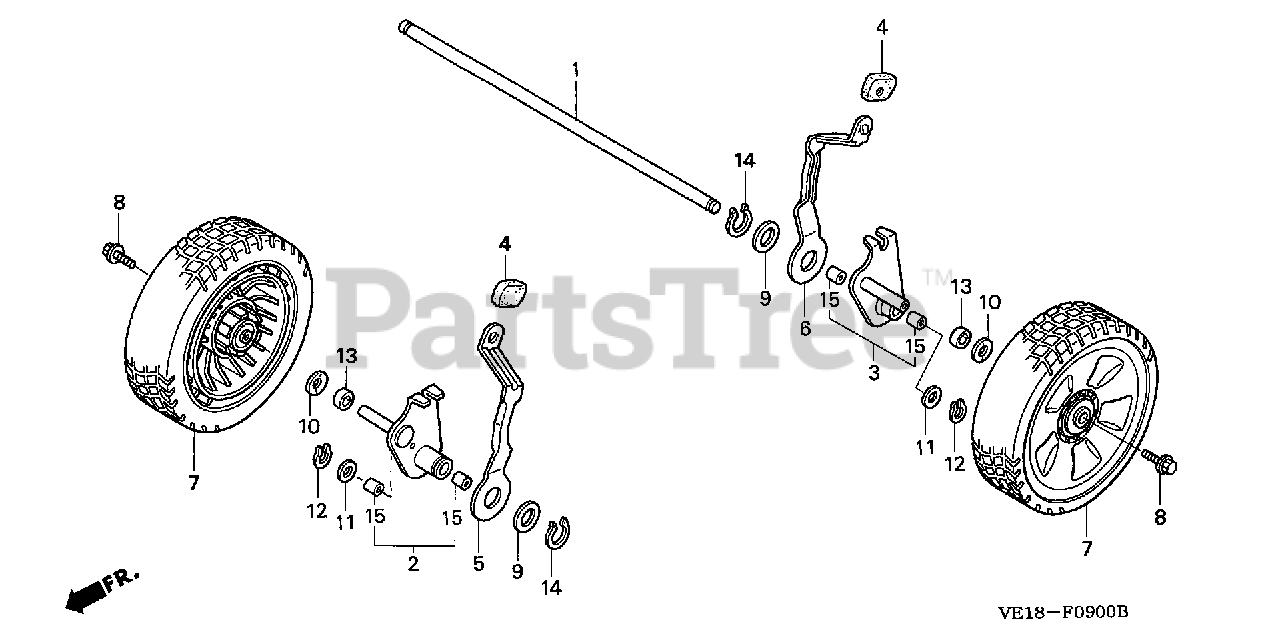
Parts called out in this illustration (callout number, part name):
1	SHAFT, WHEEL
2	ARM, R. RR. ADJUSTING
3	ARM, L. RR. ADJUSTING
4	GRIP, ADJUSTER
5	PLATE, R. RR. ADJUSTER
6	PLATE, L. RR. ADJUSTER
7	WHEEL *NH31* (MCKINLEY WHITE)
8	BOLT, WHEEL
9	WASHER, PLAIN (22MM)
10	WASHER, WHEEL
11	WASHER, THRUST (13MM)
12	CIRCLIP (OUTER) (12.7MM)
13	COLLAR, WHEEL
14	CIRCLIP (OUTER) (22MM)
15	BUSH, DRIVESHAFT
